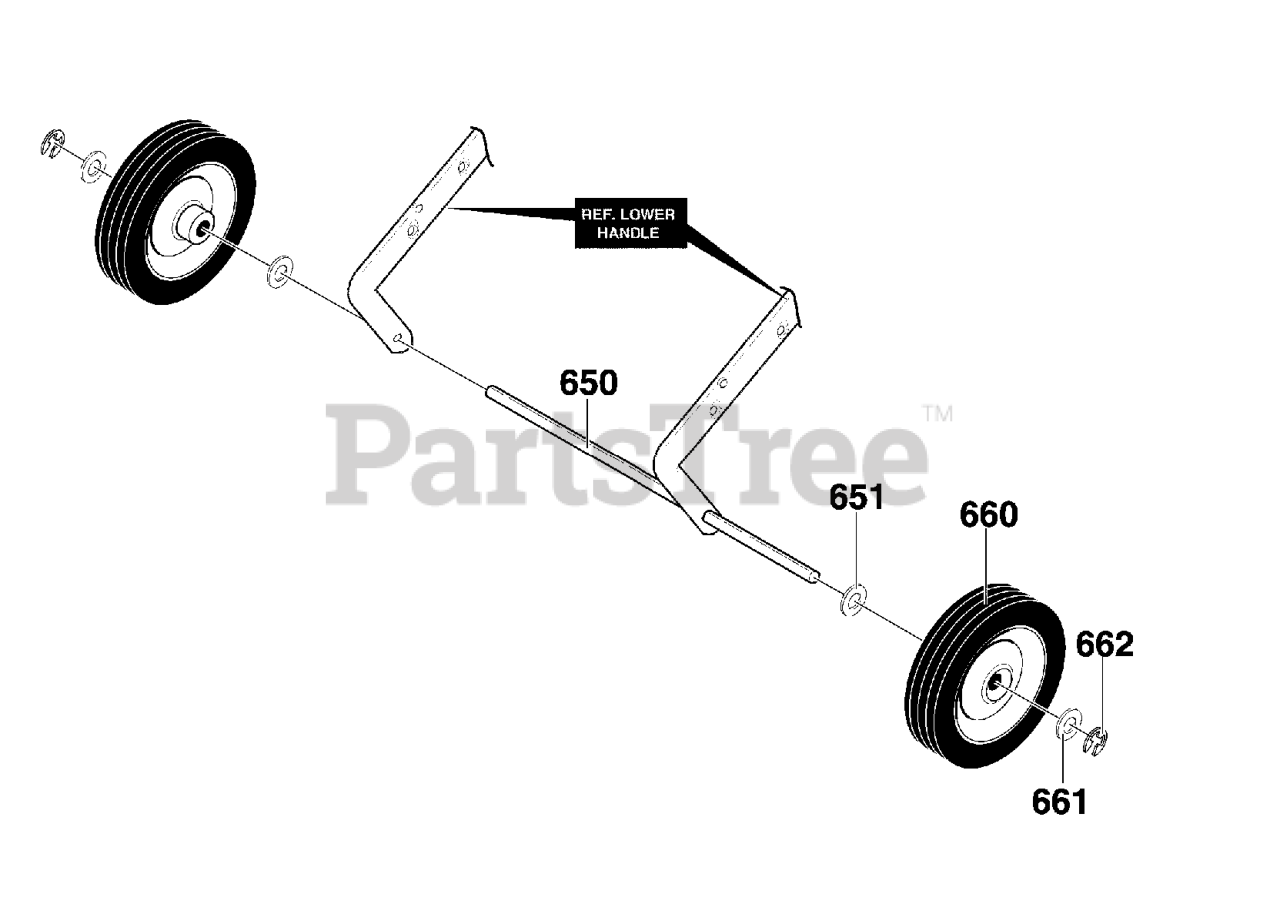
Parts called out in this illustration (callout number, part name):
650	AXLE SHAFT
651	WASHER, FLAT .391X1.00X1.25
660	TIRE & RIM
661	WASHER, FLAT .391X1.00X.125
662	RING, RET E
